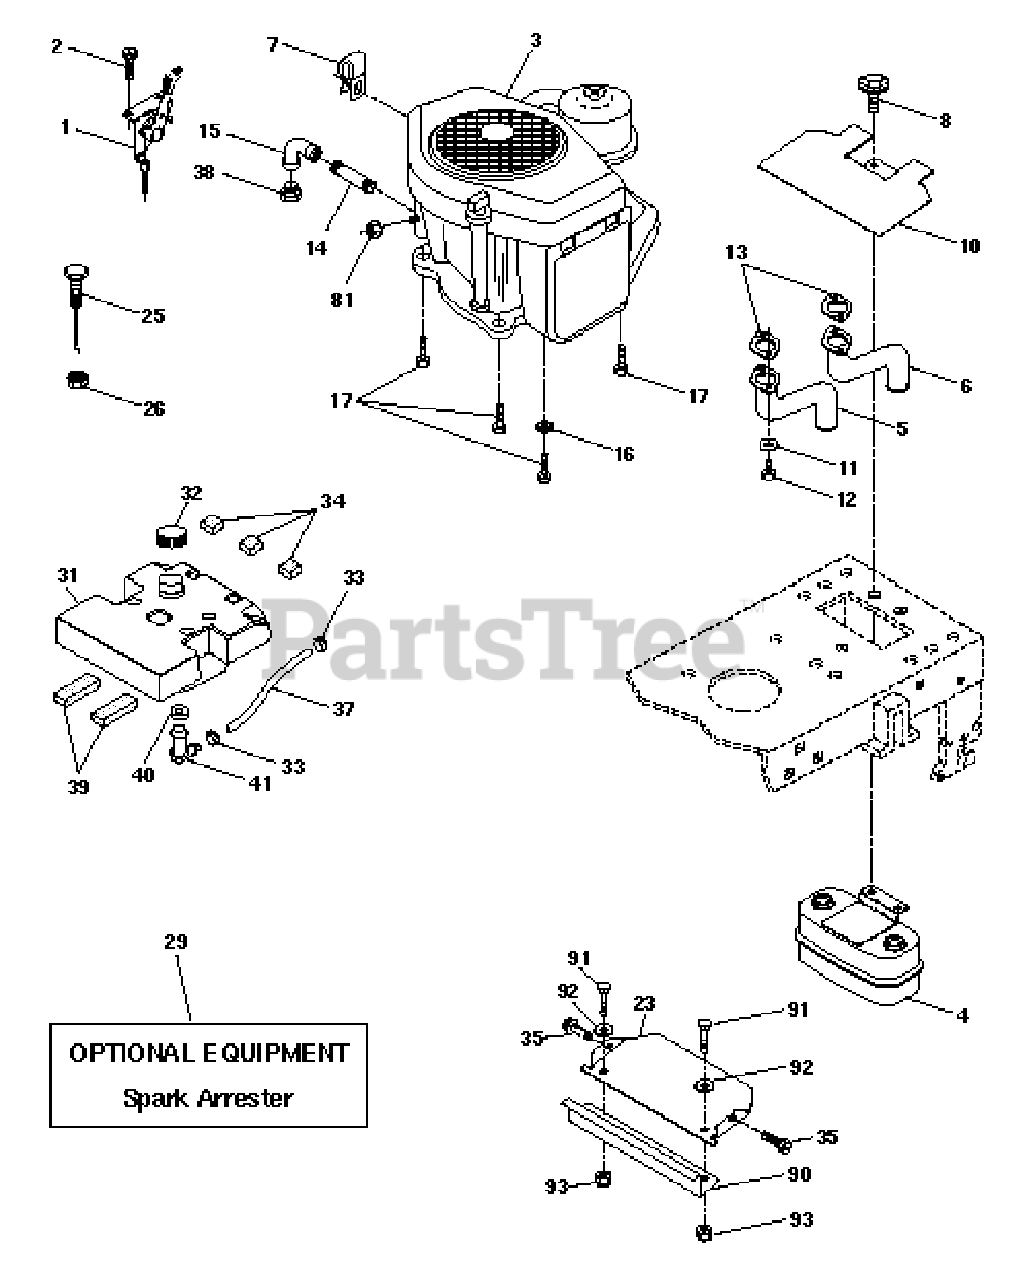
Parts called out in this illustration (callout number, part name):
1	Control Throt Flg 180 LH
2	Screw Hex Thd Cut 1/4-20x5/8 T
4	Muffler Asm Twin Lo-Tone
5	Pipe Exhaust CV18/20 LH
6	Pipe Exhaust CV18/20 RH
7	Clip, Fuel Line
8	Bolt 5/16-18unc x 3/4 W/Sems
10	Shield Heat Muffler CV18/20
13	Muffler Gasket
14	Nipple Pipe 3/8 Npt X 4-1/2"
15	Elbow Std 90 Degree 3/8-18 Npt
16	Washer Lock Ext Tooth 3/8
17	Screw Thdrol 3/8-16 x 1-1/2
23	Shield Browning
25	Choke Control 37"
26	Nut, Keps 3/8-24 Unf
29	Kit Spark Arrestor
31	Tank Fuel 3 50 Rear
32	Cap Asm Fuel Top N/Lany Vented
33	Clamp Hose Blk
34	Pad, Spacer
35	Screw Thdrol 5/16-18 x 3/4
37	Line Fuel 7.5
38	Plug Oil Drain
39	Pad, Idler
40	Bushing
41	Stem Tank Fuel
81	Nut Flange 1/4-20 Starter Nut
90	Guard Debris 97
91	Bolt Blk Fin Hex 1/4-20unc x 1/2
92	Washer 9/32 x 5/8 x 16 Ga.
93	Nut Lock 1/4 Lge Flg Gr 5 Ainc
